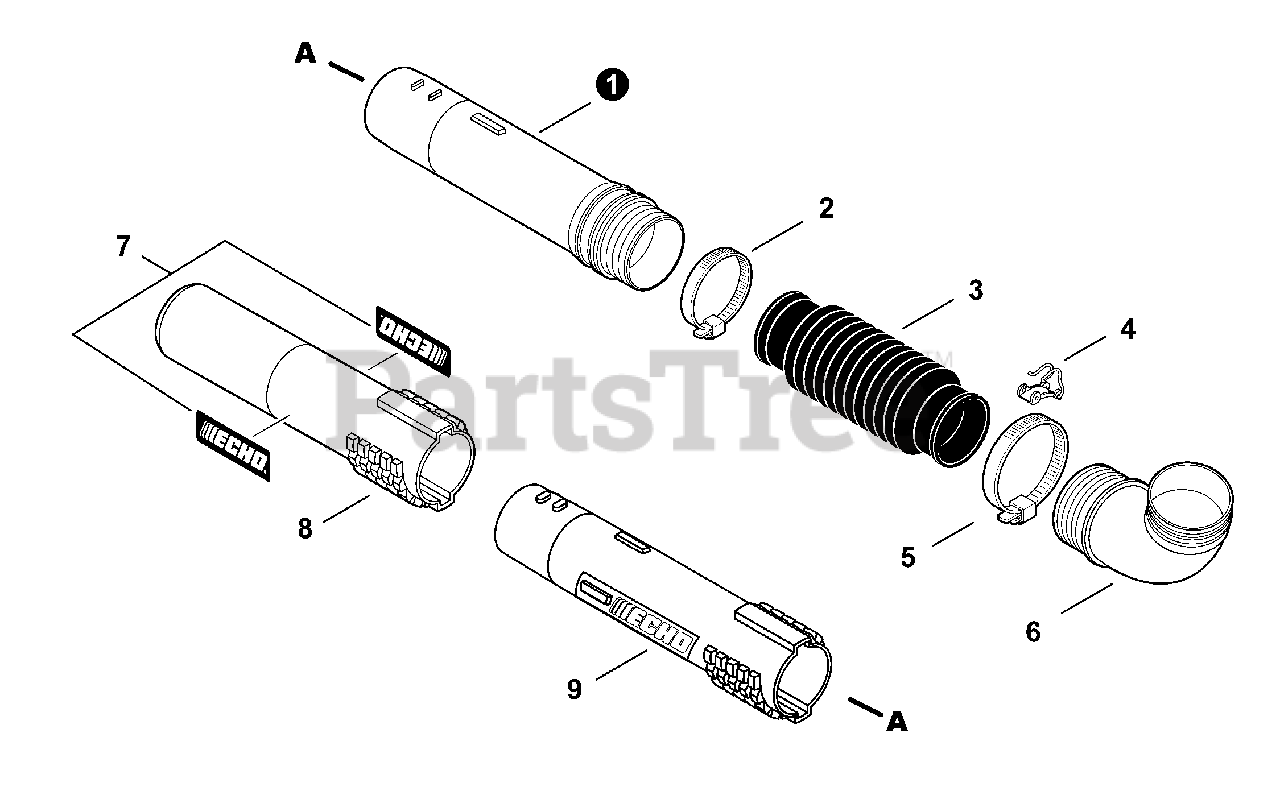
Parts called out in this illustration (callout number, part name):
1	TUBE, BLOWER - SWIVEL
2	CLAMP 58.7MM / 82.5MM
3	TUBE, BLOWER - FLEXIBLE
4	CLIP, CABLE
5	CLAMP 77.8MM /101.6MM
6	TUBE, BLOWER - ELBOW
7	LABEL, ECHO BLOWER TUBE
8	TUBE, BLOWER - NOZZLE
9	TUBE, BLOWER - STRAIGHT
